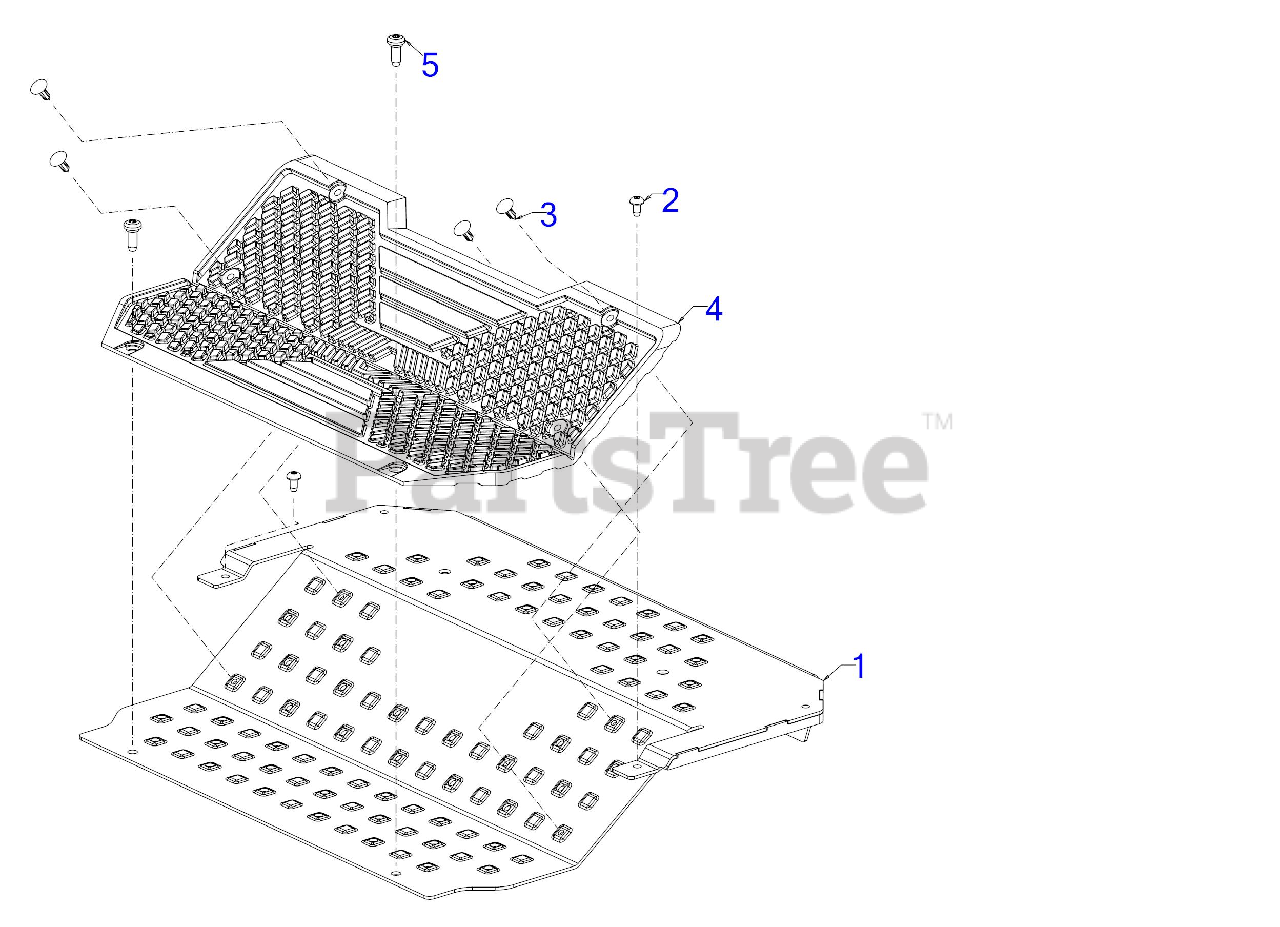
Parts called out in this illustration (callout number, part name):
2	SCREW 1/4-20 x .5
3	RATCHET CLIP .250
4	FLOORBOARD PAD
5	SHOULDER SCREW 5/16-18X.75
